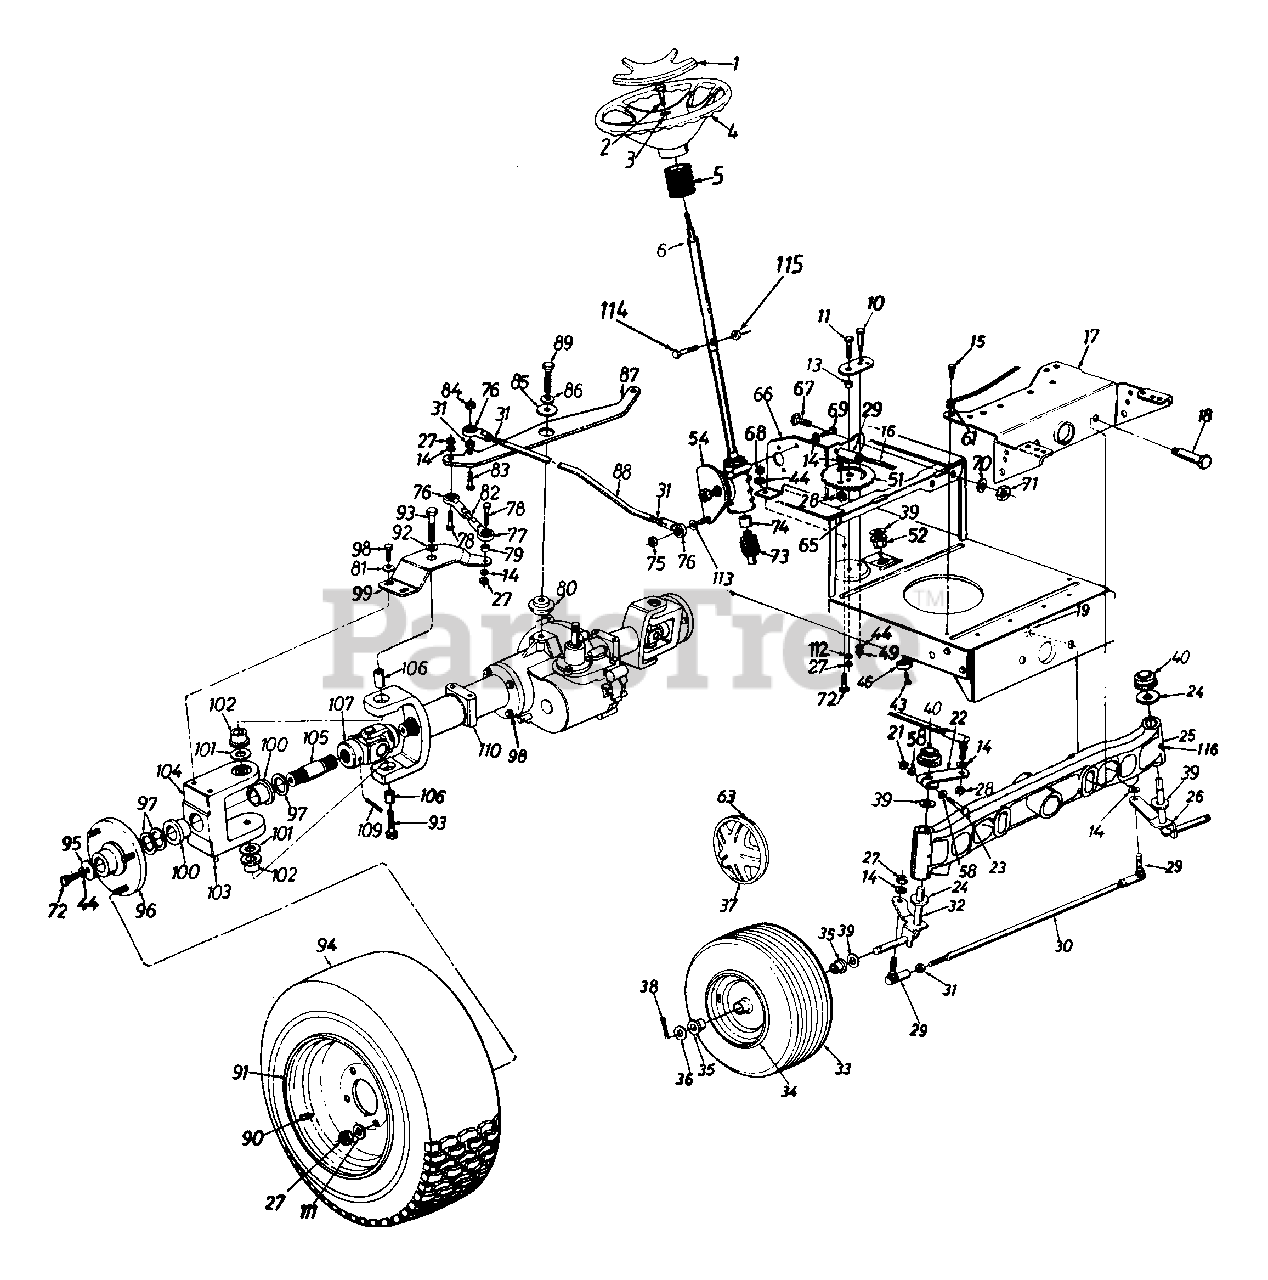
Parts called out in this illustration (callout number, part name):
1	Steering Wheel Cap
2	Hex Patch Bolt 5/16-18 x 1" Lg.
3	Belleville Wash. .345" I.D.
4	Steering Wheel
5	Steering Bellow
6	Upper Steering Shaft
10	Shoulder Bolt .437" Dia. x .35" Lg. 5/16-18 Thd.
11	Hex Bolt 3/8-24 x 1.0" Lg. (Grade 5)
13	Spacer .380" I.D. x .625" O.D. x .227"
14	L-Wash. 3/8" I.D.
15	Hex Wash. Hd. Self-Tap Scr.
16	Steering Drag Link
18	Shoulder Bolt .498" Dia. x 2.04" Lg. 3/8-16 Thd.
19	Flanged L-Nut 3/8-16 Thd.
21	Hex Cent. L-Nut 5/16-24 Thd.
22	Steering Arm Front Axle
23	Hex Bolt 5/16-24 x 2.00" Lg. (Grade 5)
25	Pivot Bar Ass'y.
26	Front Axle Ass'y. - L.H.
27	Hex Nut 3/8-24 Thd.
28	Hex Jam Nut 3/8-24 Thd.
29	Ball Joint 3/8-24 Thd.
31	Hex Jam Nut 3/8-24 Thd.
32	Front Axle Ass'y. - R.H.
35	Ball Bearing
36	Fl-Wash. .635" I.D. x 1.59" O.D.
37	Front Hub Cap
38	Cotter Pin 1/8" Dia. x 1.25" Lg.
39	Fl-Wash. .640" I.D. x .24" O.D.
43	Pan Hd. Bolt 5/16-18 x .63" Lg.
44	L-Wash. 5/16" I.D.
46	Cap
49	Hex L-Nut 5/16-18 Thd.
51	Steering Gear Segment
52	Hex Flg. Brg. .634 I.D.
54	Steering Box Ass'y. Comp.
58	Wave Wash. .32" I.D. x .62"
63	Spring Clip
65	Horizontal Cross Bracket
66	Vertical Mounting Bracket
67	Hex Bolt 1/4-28 x .75" Lg.
68	Hex Nut 5/16-24 Thd.
69	Hex Bolt 3/8-16 x 1.0" Lg.
70	Bell-Wash. .265" I.D. x .75"
71	Hex Nut 1/4-28 Thd.
72	Hex Bolt 5/16-24 x .75" Lg.
73	Pinion Shaft
74	Steering Shaft Splined Coupler
75	Hex L-Nut 3/8-24 Thd.
76	Rod End 3/8-24 Thd. - R.H.
77	Rod End 3/8-24 Thd. - L.H.
78	Hex Bolt 3/8-24 x 1.5" Lg. (Gr. 5)
79	Spacer .38" I.D. x .625"
81	Bell-Wash. .38" I.D. x .88"
83	Hex Bolt 3/8-24 x 1.25" Lg.
84	Hex Patch L-Nut 3/8-24 Thd.
85	Fl-Wash. .531" I.D. x 1.75"
86	Bell-Wash. .505" I.D. x 1.0"
89	Hex Bolt 1/2-13 x 1.5" Lg. (Gr. 5)
90	Air Valve
93	Hex Bolt 1/2-20 x 1.75" Lg. (Gr. 5)
95	Fl-Wash. .33" I.D. x 1.25"
96	Wheel Flange Ass'y.
97	Fl-Wash. 1.0" x 1.56"
98	Hex Bolt 3/8-24 x 1.25" Lg.
101	Fl-Wash. .76" I.D. x 1.5"
102	Flange Brg. 3/4" I.D.
103	Grease Fitting
104	Wheel Brg. Housing
106	Pivot Sleeve
109	Grooved Roll Pin 1.0" Lg.
110	Axle Horn Ass'y.
111	Bell-Wash. .38" I.D. x .88"
112	Bell-Wash. .39" I.D. x 1.38"
113	Fl-Wash. .385" I.D. x .62"
114	Hex Bolt 1/4-20 x 1.31" Lg.
115	Hex Ins. L-Nut 1/4-20 Thd.
116	Grease Fitting
